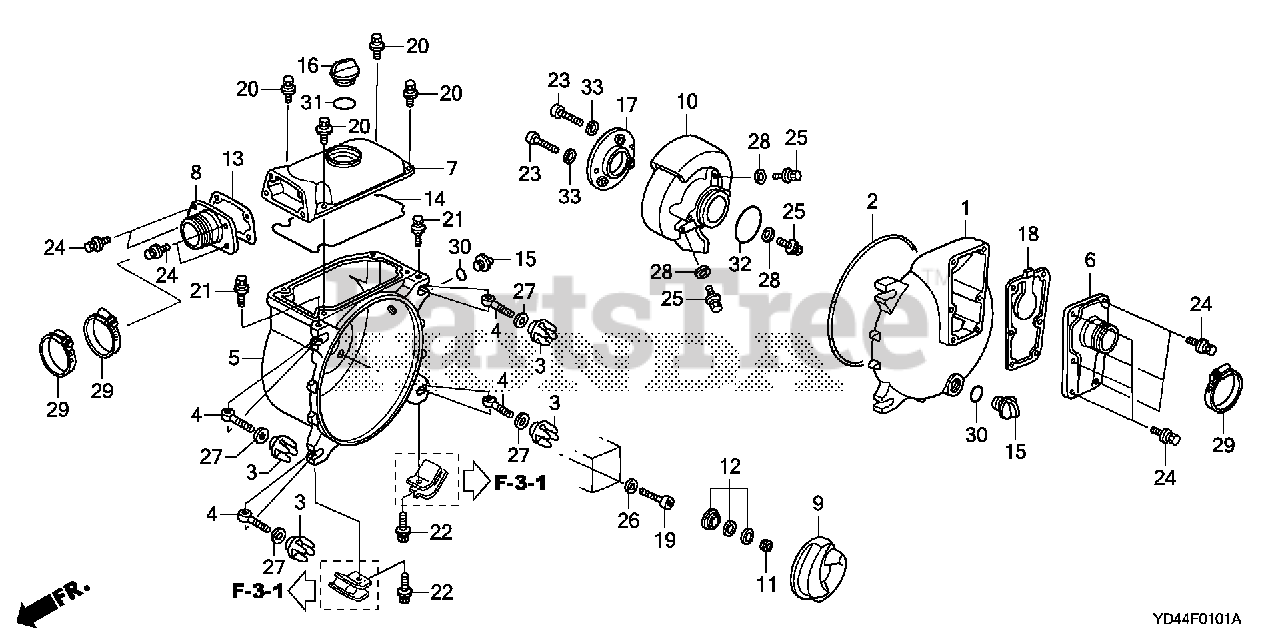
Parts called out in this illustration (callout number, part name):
1	COVER, FR.
2	GASKET, FR. COVER
3	KNOB, FR. COVER
4	BOLT, FR. COVER SETTING
10	CASE, VOLUTE
11	WASHER, SHIM
12	SEAL ASSY., MECHANICAL
13	GASKET, OUTLET
14	GASKET, HEAD
15	CAP, PLUG (32MM)
16	CAP, PLUG (40MM)
17	PLATE, WEAR
18	GASKET, HOSE COUPLING
19	BOLT, SOCKET (8X50)
20	BOLT-WASHER (10X30)
21	BOLT-WASHER (12X45)
22	BOLT-WASHER (12X50)
23	BOLT, SOCKET (8X35)
24	BOLT-WASHER (12X35)
25	BOLT-WASHER (6X20)
26	WASHER (8MM) (AL.)
27	WASHER, PLAIN
28	WASHER, PLAIN (6MM)
30	O-RING (32MM)
31	O-RING (40MM)
33	WASHER, CLUTCH (8MM)
